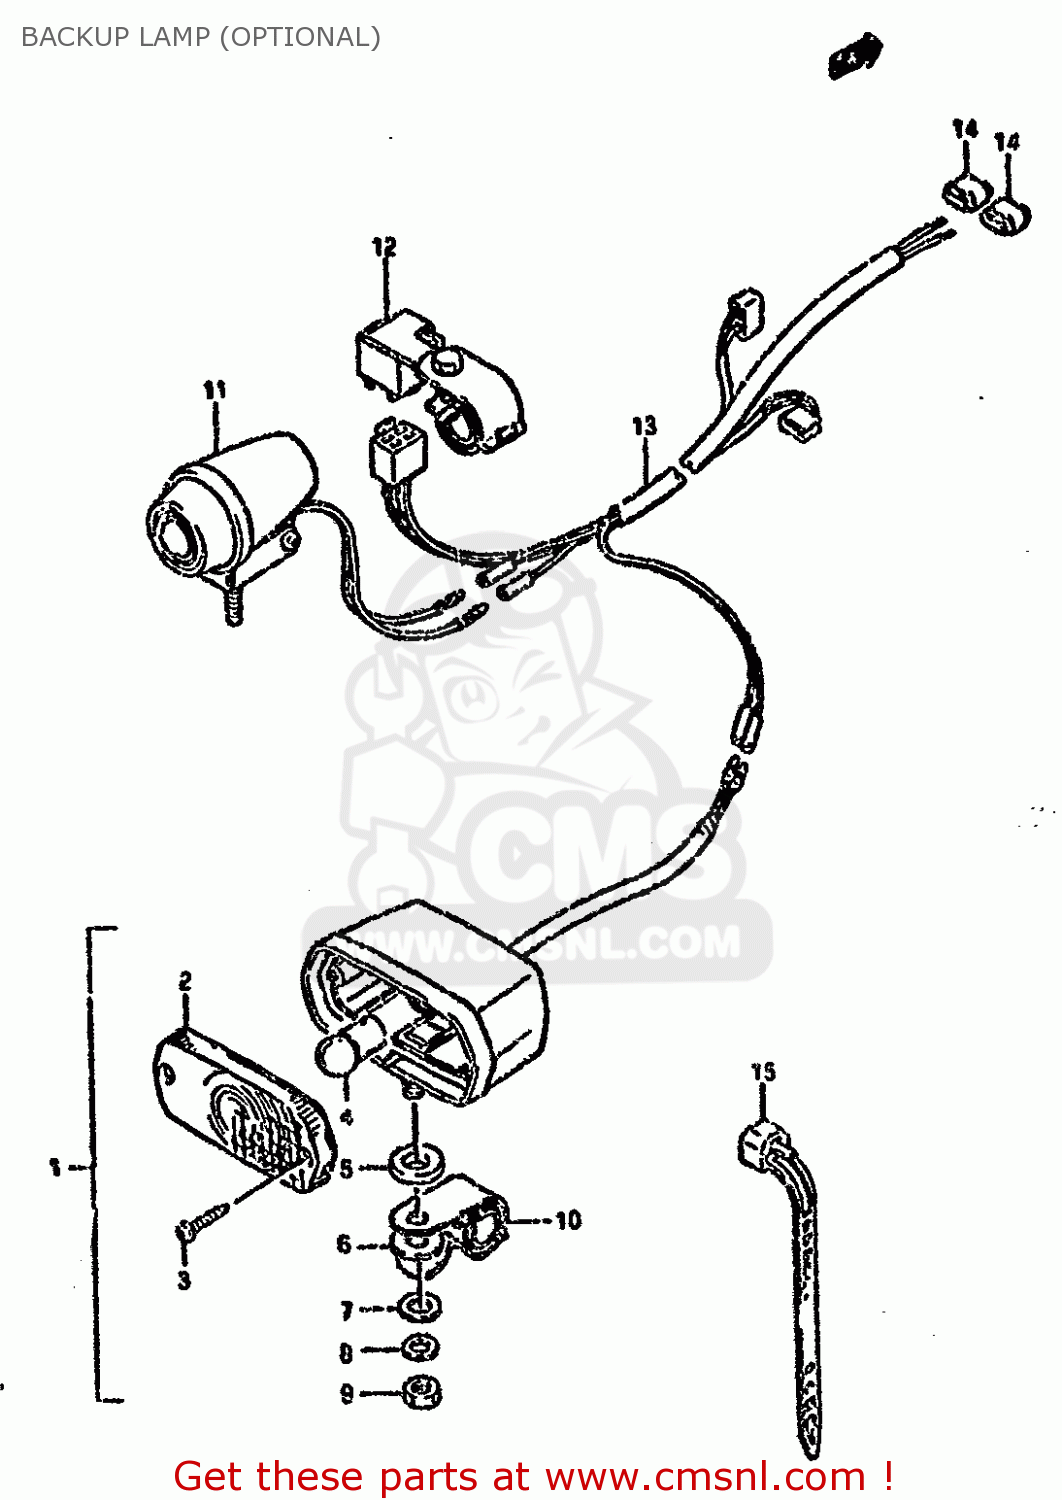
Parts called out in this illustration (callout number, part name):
1	LAMP ASSY,BACK UP
2	LENS,BACK UP LAMP
3	SCREW,BACKUP LAMP
4	CLAMP L:165
5	CUSHION NO.1
6	CUSHION NO.2
7	WASHER
8	FUSE(20A)
9	NUT
10	FUSE(15A)
11	BUZZER ASSY,BACKUP
12	BOLT
13	WASHER,LOCK
14	CONNECTOR,LEAD WIRE
15	CLAMP(L:125)
16	MASCOT,KEY
17	SWITCH ASSY,EMERGENCY
18	WIRE,EMERGENCY SWITCH
19	HORN ASSEMBLY
20	SWITCH ASSY,HORN
21	BOX ASSY,FUSE
22	BRACKET,TURN SIGNAL RELAY
23	SCREW
24	WASHER,LOCK
25	WASHER,COVER,FRONT
26	KEY,BLANK(TYPE:C)
27	PLUG ASSY,POWER SOURCE
28	WIRE,HORN LEAD
29	CONNECTOR,LEAD WIRE
30	LEAD WIRE,HORN SWITCH (ORANGE)
31	WIRE,HORN SWITCH LEAD
32	LEAD WIRE,EMERGENCY SWITCH
